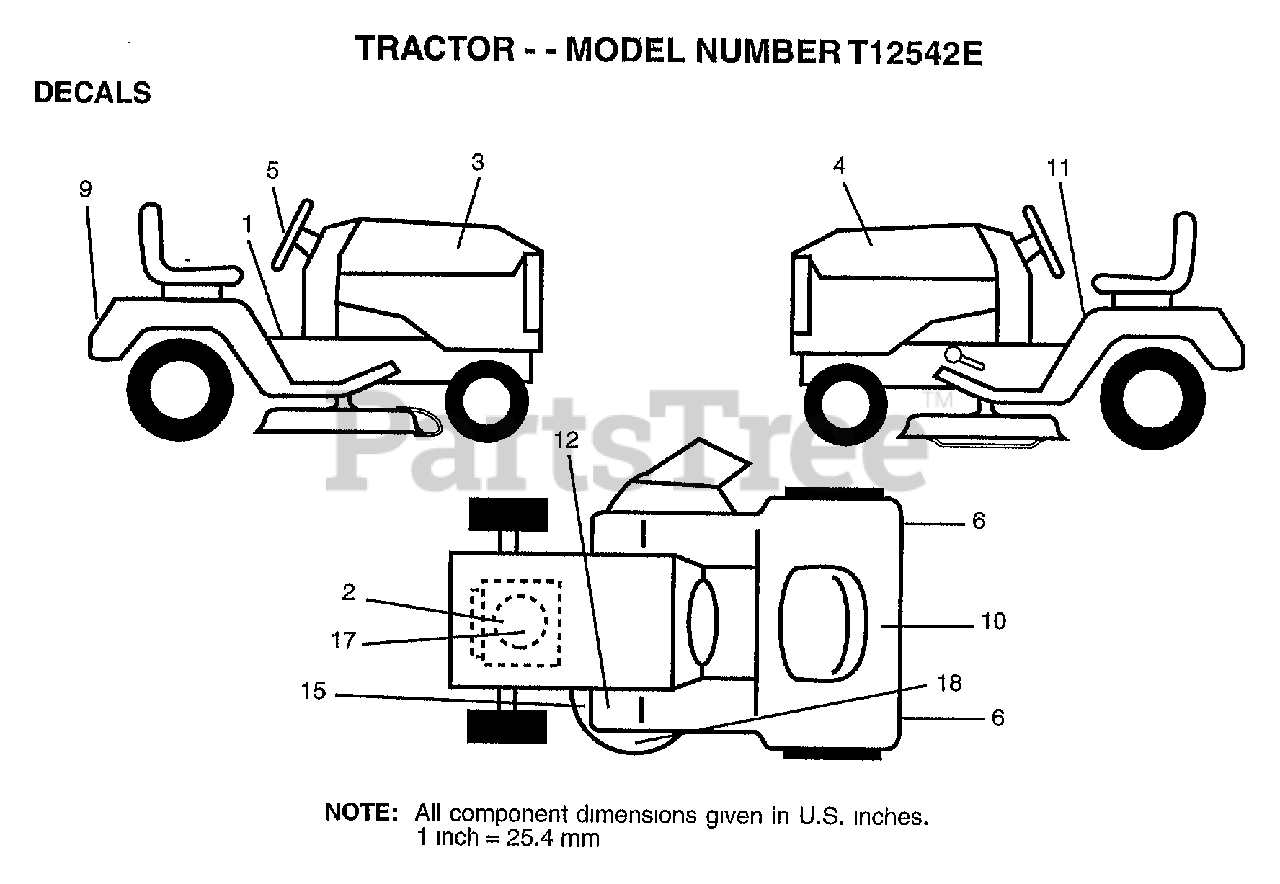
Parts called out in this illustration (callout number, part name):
1	"DECAL DASH,OPER."
2	DECAL, HP ENGINE
3	DECAL.HD.RH.12.5
4	DECAL.HD.LH.12.5
5	"DECAL,STR WHL T"
6	REFLECTOR-TAIL YT
9	DECAL.FENDER
10	DECAL.BATRY.3-3908
11	"DECAL DANGER,FEND"
15	DECAL
